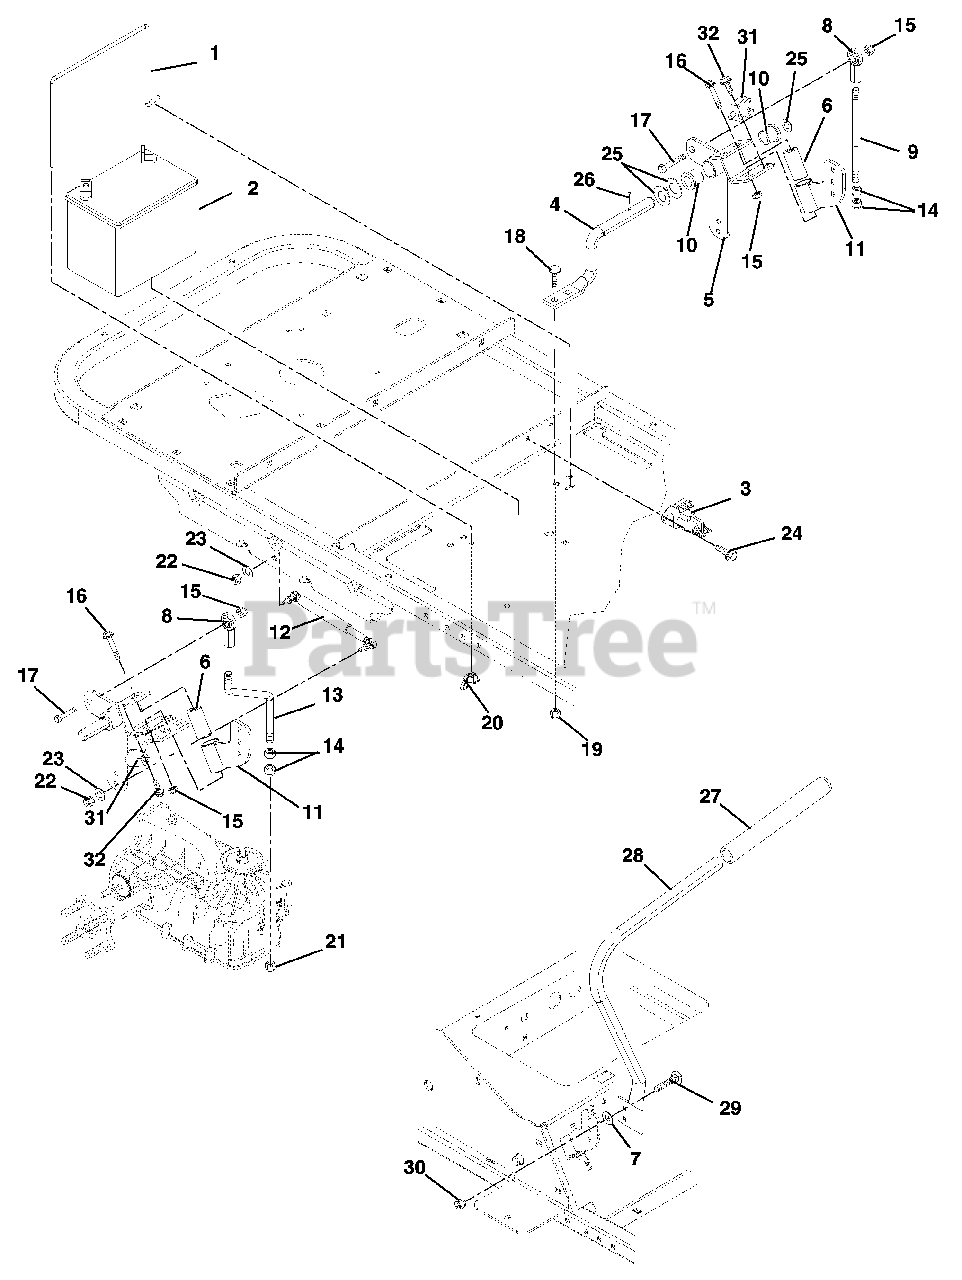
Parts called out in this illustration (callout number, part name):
1	BATTERY ROD
2	BATTERY, 300 CCA 10U1L
2	BATTERY W/ TUBE
3	SOLENOID
4	ROD PIVOT
5	WMT, CONTROL
6	BSHG, SPCR .502X.997X2.03 PM
7	@WSHR-LK-EXT.326X.599X.031YWZC
8	ROD END, 1/2 RH
9	ROD-TRANSAXLE LH
10	BUSHING-1"X.75"X1"
11	WMT, HANDLEBAR
12	DAMPENER
13	ROD-TRANSAXLE RH
14	NUT-JAM .50-20 GR2 YWZC
15	@NUT-LK-TOP-FLG .50-13 YWZC
16	@BLT-HEX .50-13X3.00 GR5 YWZC
17	@BLT-HEX .50-13X1.50 GR5 YWZC
18	BLT-RDHDSQNK .38-16X1.00 G5BZ
19	NUT-LK-TOP-FLG .38-16 BLKZC
20	NUT-LK WING .250-20 YWZC
21	NUT-LK-JAM-NYL .50-20 GR2 YWZC
22	NUT-HEX M8-1.25 YWZC
23	@WSHR-LK .31X.078 REG YWZC
24	@SCR-TAP .25-20X.37 HWH YWZ TR
25	WSHR-FL-STL .754X1.000X.032 YZ
26	PIN-ROLL .188X1.13
27	GRIP - HANDLEBAR
28	HANDLEBAR WLDM'T RH
28	HANDLEBAR WLDM'T LH
29	BLT-RDHDSQNK.31-18X.88 GR5YWZC
30	@NUT-LK-TOP-FLG .31-18 YWZC
31	SWITCH- DOUBLE POLE N.O./N.O.
32	@SCR-TAP 10-24X.50 HWH TR YWZC
